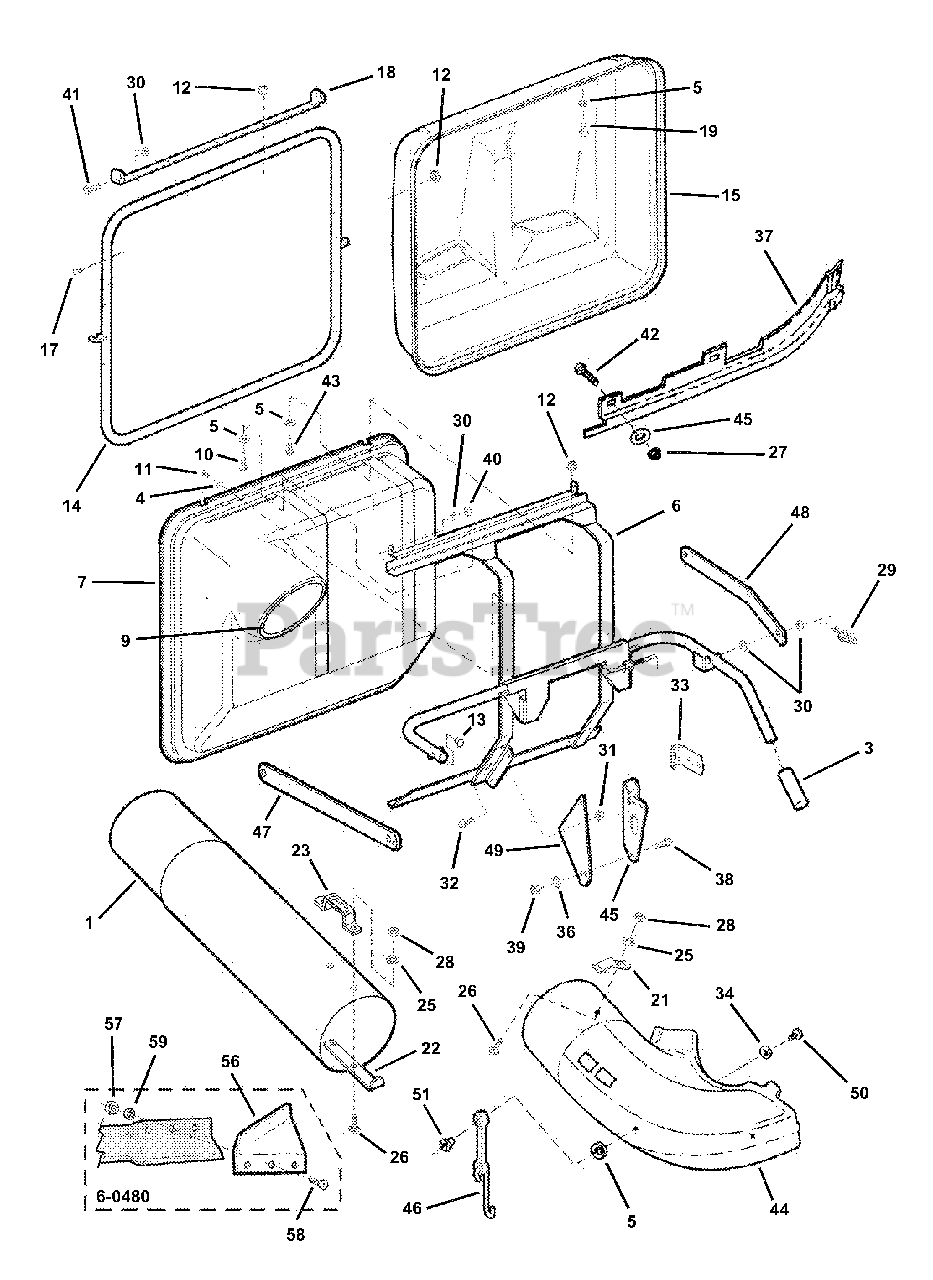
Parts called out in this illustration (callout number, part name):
1	TUBE, Grass (23-3/4" long)
3	GRIP
4	WASHER, 11/32 Flat
5	WASHER, 3/16 Flat (3 in hardware bag)
6	WELDMENT, Front Cover Brace
7	COVER, Front
9	GASKET, Chute
10	SCREW, #10-24 x 1/2" Hex Washer Self-Tap (Torx)
11	SCREW, 1/4-20 x 5/8" Pan Head Self-Tapping
12	NUT, #10-24 Hex Fl. Lock
13	END CAP, Tube
14	WELDMENT, Rear Cover Brace
15	COVER, Rear
17	BOLT, #10-24 x 1-1/2" Oval Head
18	HINGE, Rear Cover
19	SCREW, #10-24 x 1-1/2" Machine
21	LATCH, Chute/Tube
22	BASE, Handle
23	HANDLE, Tube
25	WASHER, 1/4 Internal Tooth Lock
26	BOLT, 1/4-20 x 3/4" Round Hd. Short Nk. Carriage, Gr. 5
27	NUT, 5/16-18 Hex Ctr. Lock
28	NUT, 1/4-20 Hex
29	PIN, 3/8 Self Lock Cotter
30	WASHER, 3/8" Flat
31	NUT, 5/16-18 Flange Lock
32	BOLT, 5/16-18 x 5/8" Hex Flange Lock
33	SUPPORT, Bumper
34	WASHER, .219 I.D. Flat
36	WASHER, 1/2 Internal Tooth Lock
37	BAFFLE, 38 Deck MY 97
38	BOLT, 1/2-13 x 1" Hex Head Cap Grade 5
39	NUT, 1/2-13 Hex Grade B
40	NUT, 3/8-16 Hex Lock
41	SCREW, 3/8-16 x 1" Hex Head Cap, Grade 5
42	SCREW, 5/16-18 x 3/4" Hex Head Cap, Grade 5
43	BOLT, #10-24 x 3/4" Hex Flange Lock, Grade 5
44	ASS'Y, Chute
45	BRACE, Bumper
46	STRAP, Bag Adap./Tube
47	LINK, Handle (Right Hand)
48	LINK, Handle (Left Hand)
49	PLATE, Hitch
50	SCREW, 10/24 x 5/8" Pan Head
51	NUT, Weld- 10/24 Thread
56	Air Lift
57	NUT, 5/16-24 Hex
58	SCREW, 5/16-24 x 5/8" Oval Head Machine
59	WASHER, 5/16 Int. Tooth Lock
